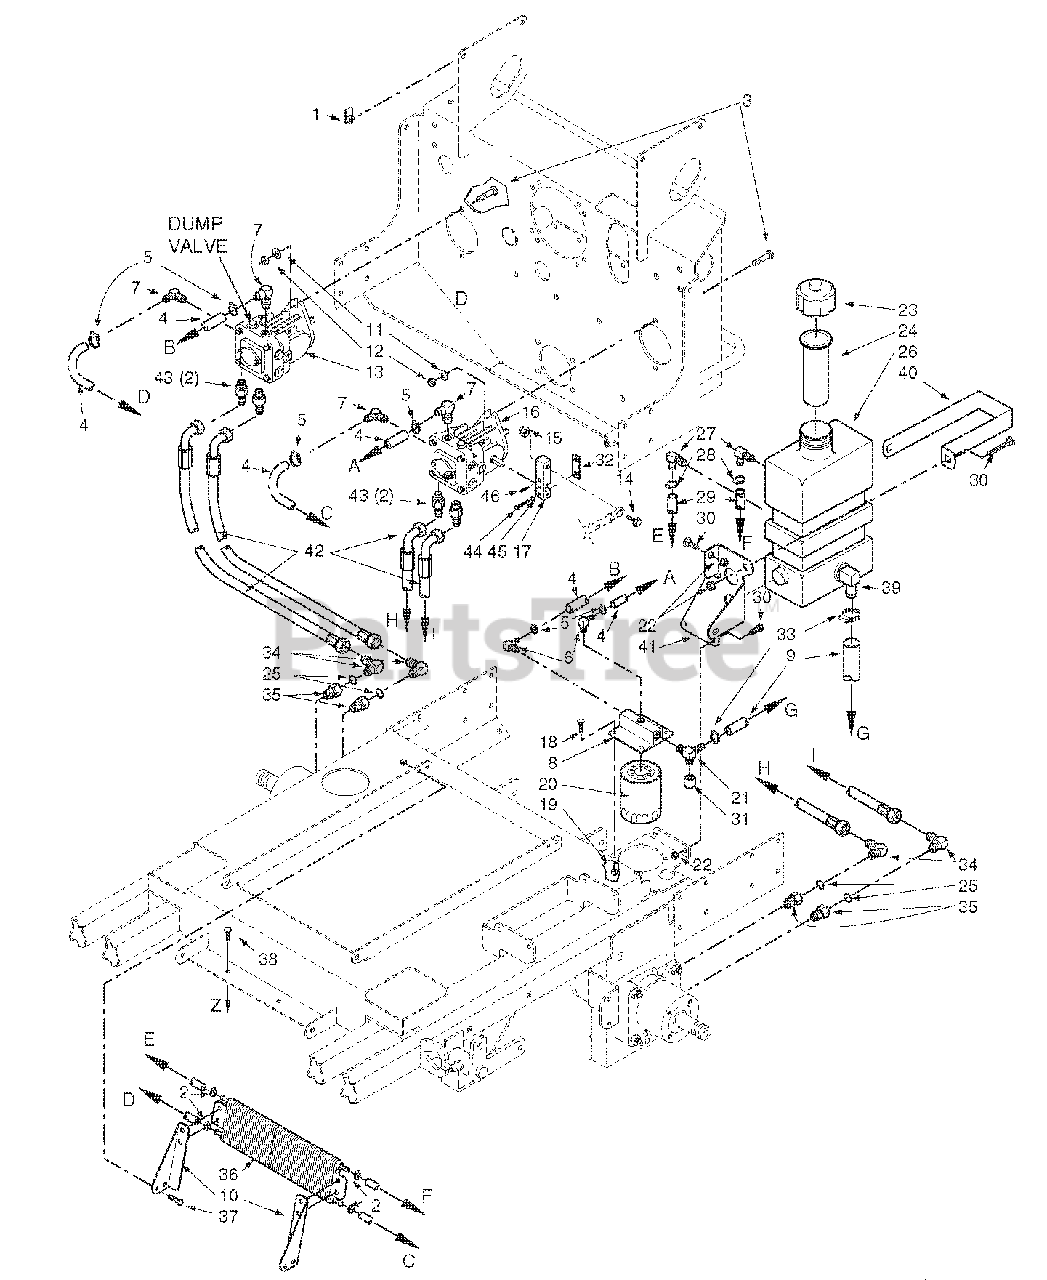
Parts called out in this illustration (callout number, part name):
1	U-Nut 1/4-20
2	Hose Clamp, 0.69" Dia.
3	Bolt, Hex Head 1/4-20 x 2.0"
4	Hose, 3/8" ID Pushlock
5	Clamp, Hose 1/2"
6	Elbow, 90 Degree - 1/4" NPT x 3/8" Hose
7	Elbow, 90 Degree - 9/16" O-Ring x 3/8" Hose
8	Oil Filter Base
9	Hose Assembly, 1/2" ID
10	Mounting Bracket - LH, Oil Cooler
10	Mounting Bracket - RH, Oil Cooler
11	Flatwasher, 3/8" (.391 x .938 x .105") Grade 8
12	Nut, Hex Elastic Stop 3/8-16
13	Pump, Right Hand
13	Pump w/Fan, Right Hand
14	Bolt, Hex Head, 3/8-16 x 1-1/4"
15	Nut, Hex, Elastic Stop 3/8-16
16	Pump, Left Hand
16	Pump w/Fan, Left Hand
17	Block, Pump Control
18	Bolt, Hex Head 5/16-18 x 1.0" Zinc
19	Nut, Serrated Flange 5/16-18
20	Oil Filter
21	Tee, 3/4" O-Ring x JIC x 1/2" Hose
22	Nut, Hex Elastic Stop 1/4-20
23	Cap, Hydraulic Tank
24	Insert, Filler Neck
25	O-Ring
26	Oil Reservoir Assembly
27	Elbow, 90 Degree .38" Hose
28	Hose Clamp, 0.69" Dia.
29	Hose, 3/8" ID, Pushlock
30	Screw, Phillips Head, 1/4-20
32	Clamp Plate, Pump Control
33	Clamp, Hose
34	Elbow, 90 Degree, 1/2" x 1/2"
34	Elbow, 90 Degree, 5/8" x 1/2"
35	Bushing, 7/8"-14 JIC x 3/4"-16 O-Ring
36	Cooler, Oil
37	Bolt, Hex Head 5/16-18 x 3/4"
38	Bolt, Carraige 1/4-20 x 3/4"
39	Elbow, 90 Degree
40	Strap, Hydraulic Tank
41	Support Bracket, Hydraulic Tank
42	Hose Assembly, Pump
43	Union, 3/4"-16 JIC x 3/4"-16 O-Ring
44	Bolt, Hex Head, 1/4-20 x 1-1/4"
45	Lockwasher, 1/4" Spring
46	Roll Pin, Spring 3/16 x 3/4"
